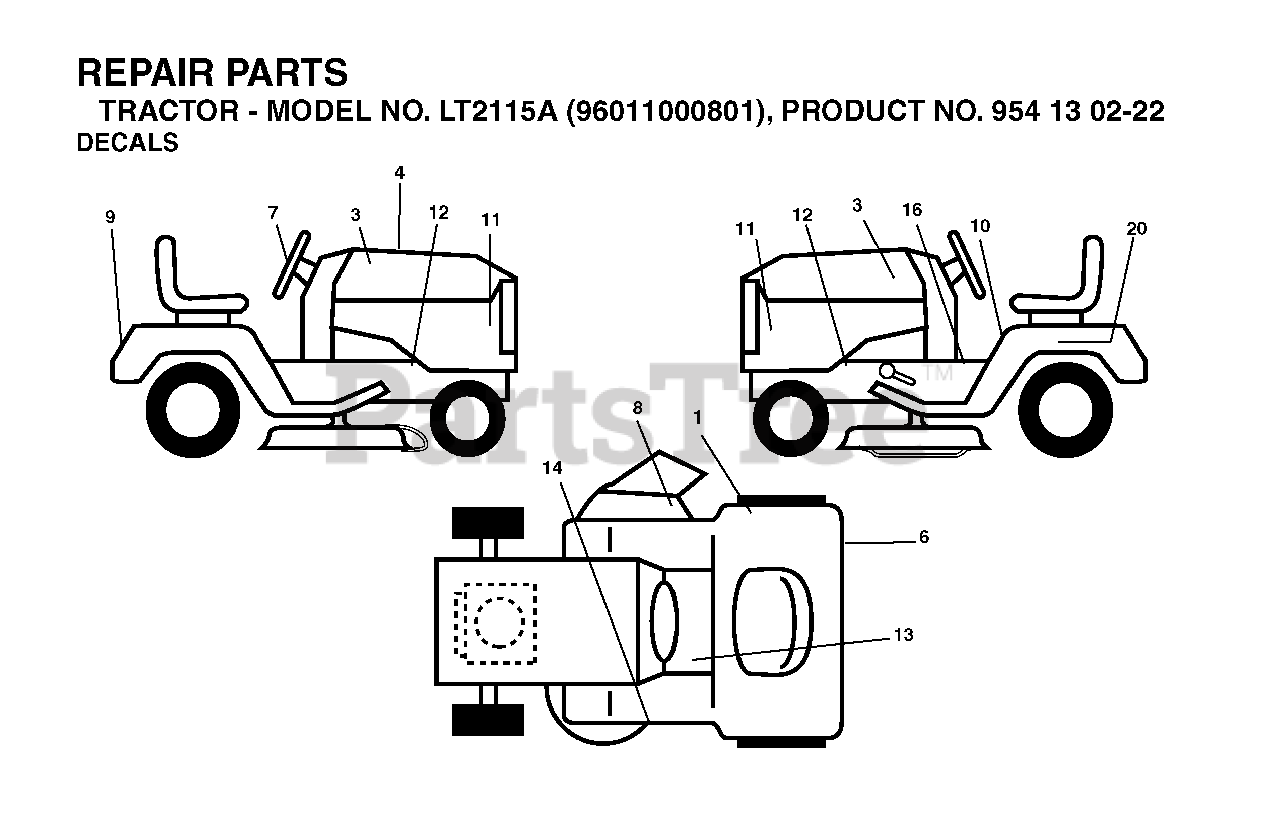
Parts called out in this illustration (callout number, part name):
8	DECAL.INTERNATIONL.CUTFINGER
10	DECAL READ OWNER'S MAN SYMS
14	DECAL V-BELT SCHEMATIC
16	DECAL PARK BRAKE
20	DECAL BTRY SYMBOLS
